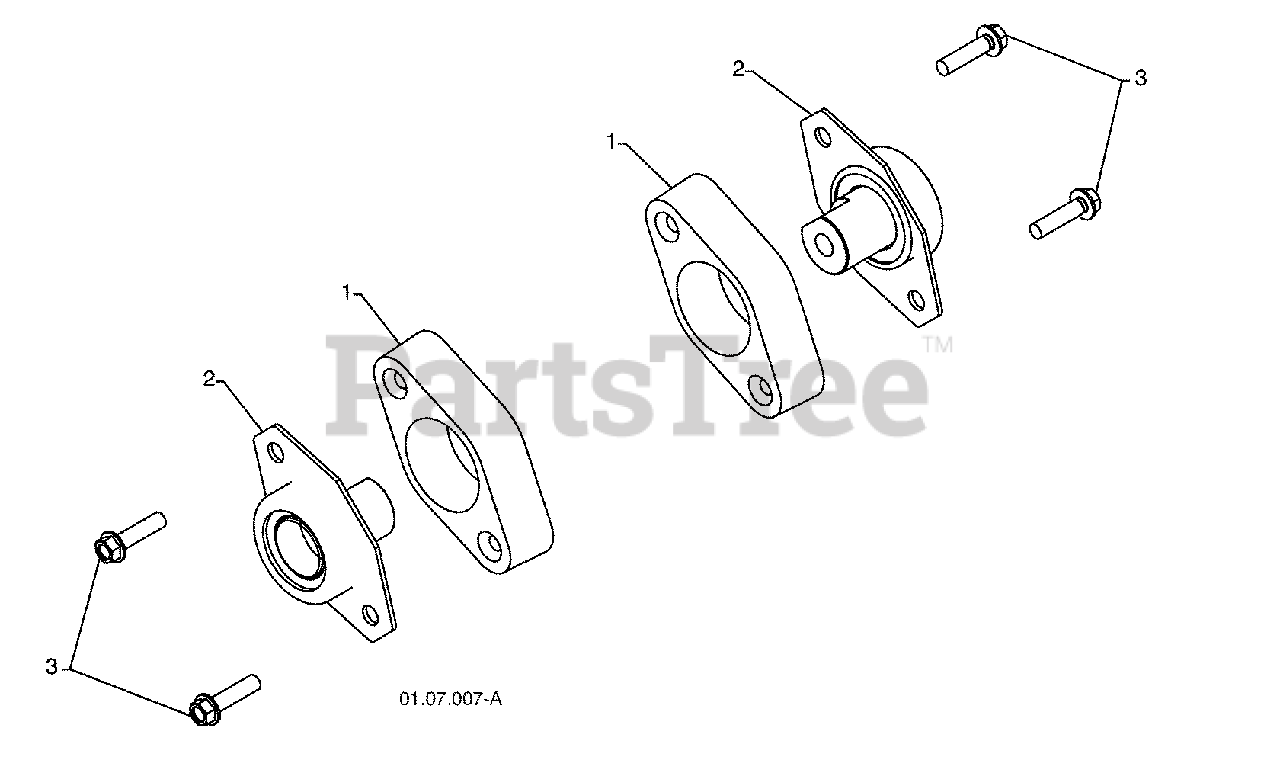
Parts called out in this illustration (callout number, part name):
1	PLASTIC RETAINER
2	AUGER BALL BEARING
3	SCREW 5/16--18 X 1.00
